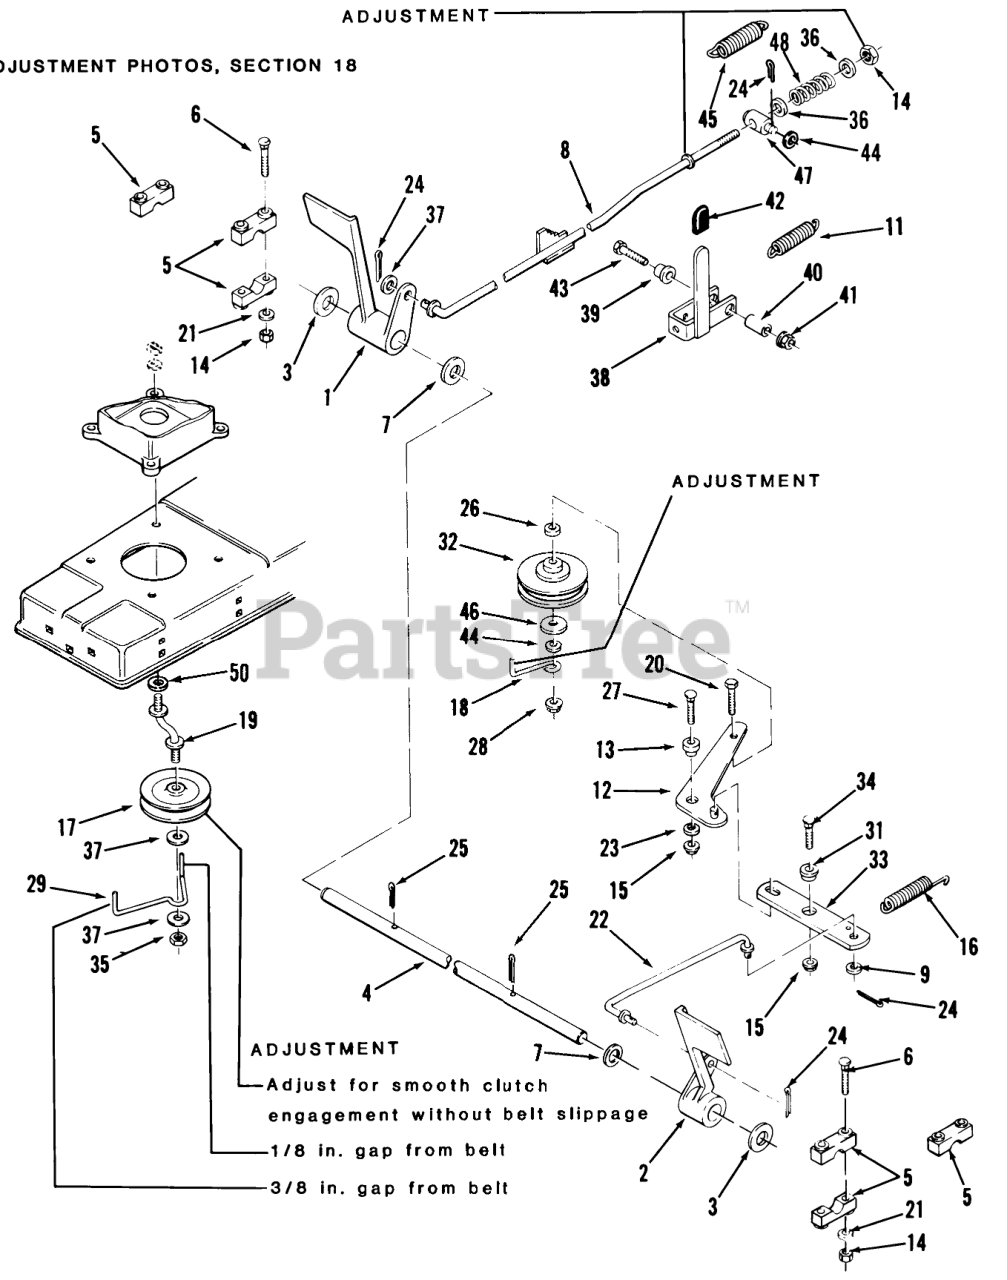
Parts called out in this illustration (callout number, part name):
1	PEDAL-BRAKE R
2	PEDAL CLUTCH R
3	Special Washer
4	SHAFT-PEDAL
5	BLOCK PIVOT
6	Washer
7	Washer
8	Brake Rod 208-3, 211-3 Only
9	WASHER 5/16 SAE
11	SPRING-EXTENSION
12	IDLER ARM ASSY R
13	SPACER-IDLER ARM
14	Nut
15	LOCKNUT-FLANGE
16	SPRING
17	PULLEY-IDLER STATION
18	RETAINER-BELT
20	Bolt
21	WASHER 5/16 SAE
22	ROD-CLUTCH R
23	Washer
24	Pop Rivet
26	SPACER
27	Carriage Bolt
28	LOCKNUT-FLANGE
29	RETAINER-BELT
31	SPACER
32	IDLER PULLEY
33	BAR-CLUTCH
34	Bolt
35	Nut
36	Collar
37	Washer
38	PAWL & HANDLE ASSY
39	SPACER
40	SPACER
41	LOCKNUT-FLANGE
42	GRIP
43	Bolt
44	Washer
45	SPRING-EXTENSION
46	WASHER
47	TRUNNION-LIFT
48	SPRING FRICTION
50	Washer-Lock
